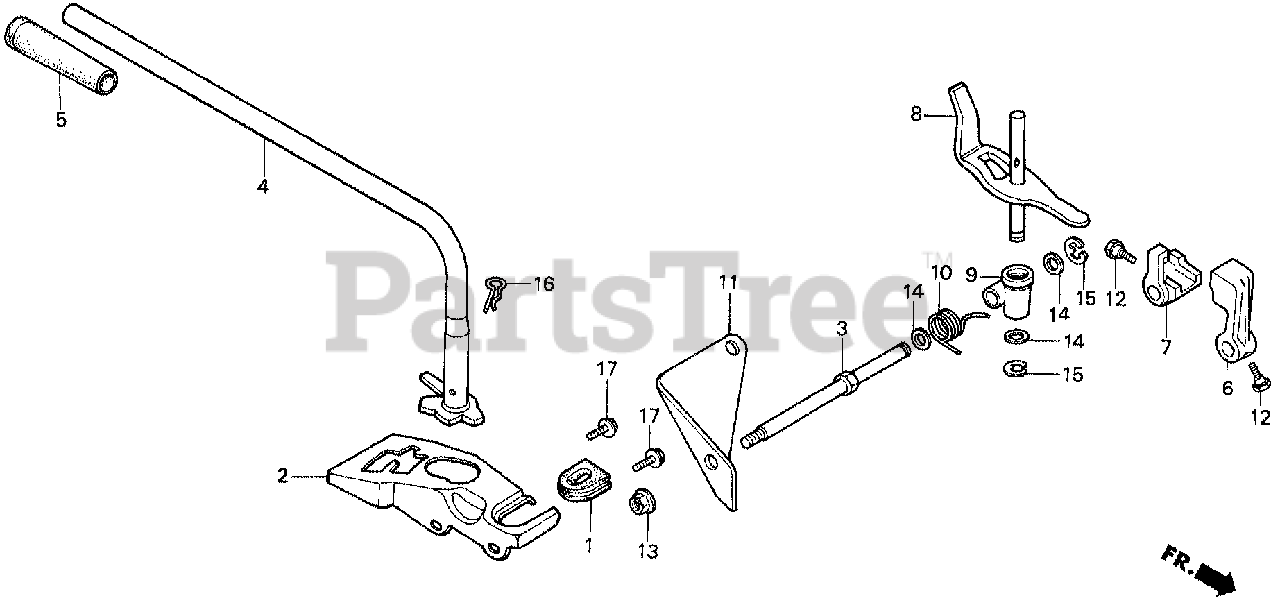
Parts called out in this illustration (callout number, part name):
1	GROMMET, WIRE
2	COVER, CHANGE
3	BOLT, HOLDER
4	LEVER, CHANGE
5	GRIP, CHANGE LEVER
6	ARM A, CHANGE
7	ARM B, CHANGE
8	LEVER, SELECT
9	HOLDER, SELECT LEVER
10	SPRING, CHANGE LEVER RETURN
11	BRACKET, REVERSE STOP
12	SCREW, FORK SETTING
13	NUT, FLANGE (10MM)
14	WASHER, PLAIN (12MM)
15	E-RING (10MM)
16	PIN, LOCK (12MM)
17	BOLT, FLANGE (6X12)
